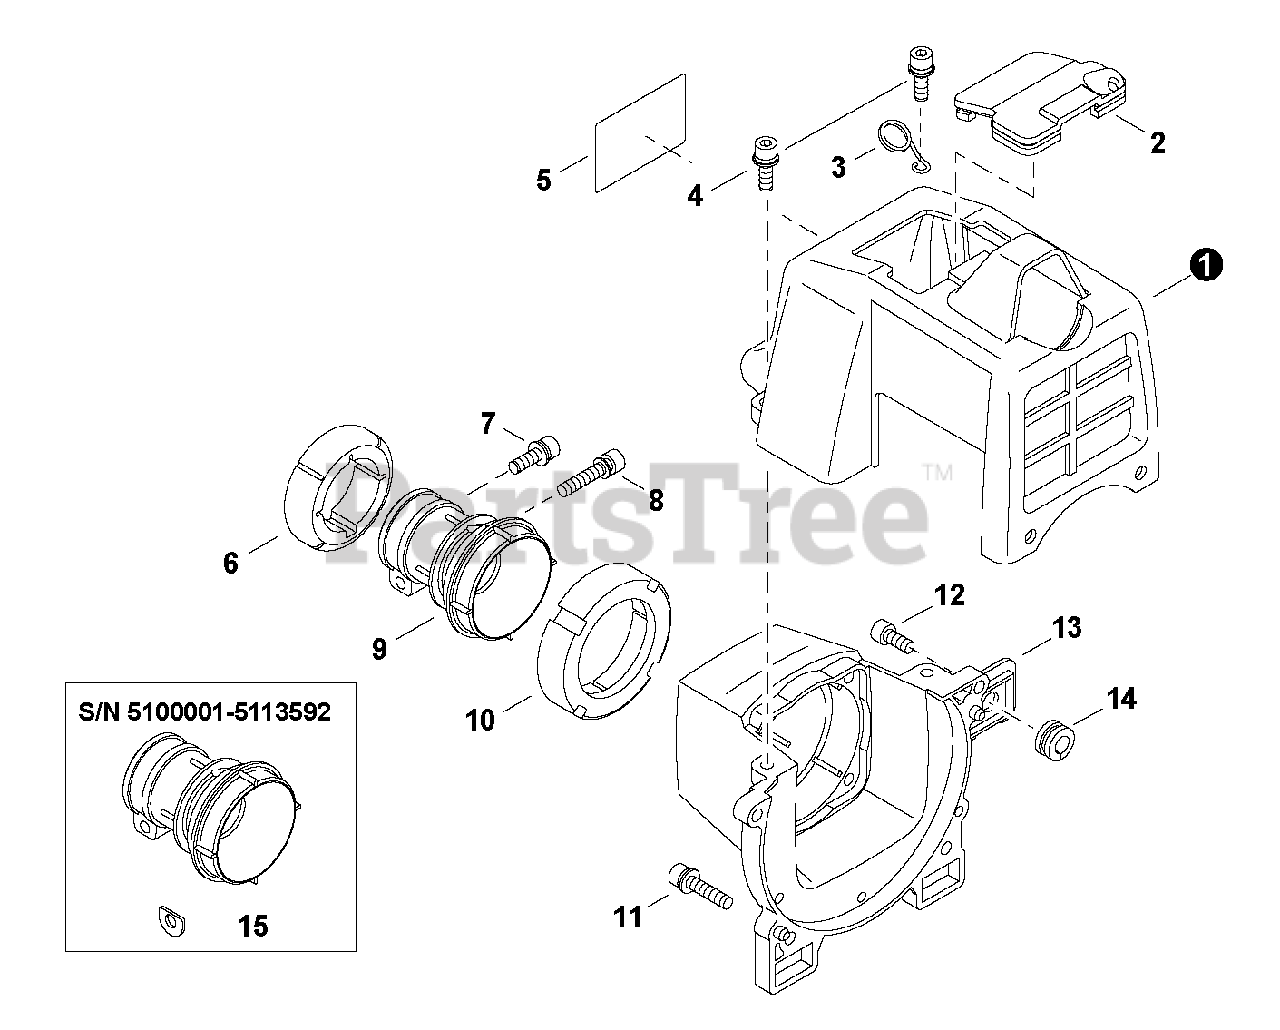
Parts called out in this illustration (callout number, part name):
1	Cover, Engine
2	Cap, Dust
3	Holder, Throttle Cable
4	Bolt M5x16
5	Label, Model
6	Holder, Front Cushion
7	Bolt M5x16
8	Bolt M6x28
9	Cushion
10	Holder, Rear Cushion
11	Bolt M5x30
12	Bolt M5x18
13	Cover, Fan
14	Grommet
